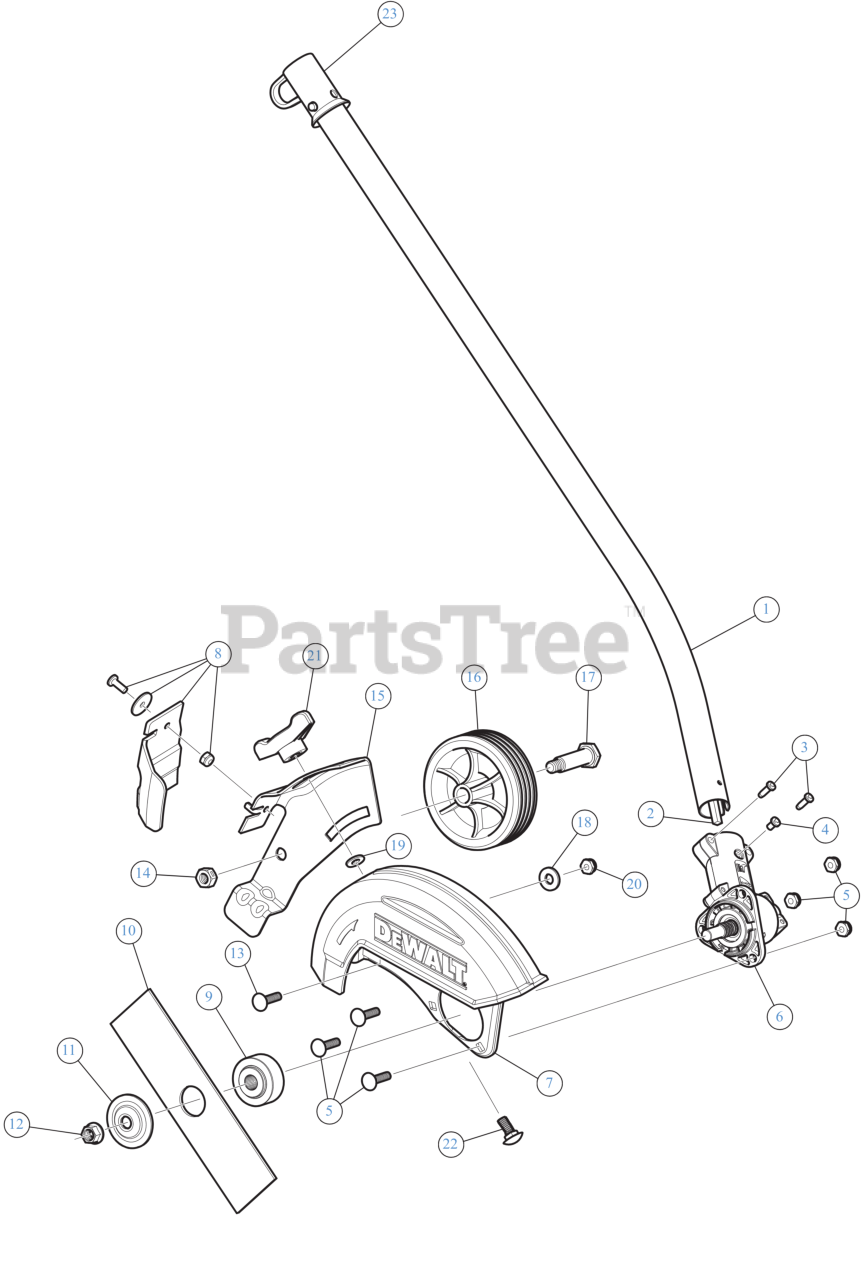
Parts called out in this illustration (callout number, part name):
1	BOOM ASSEMBLY
2	LOWER DRIVE SHAFT
3	SCREW #
4	SCREW, 8-32 x .312 P
5	BLADE LOCK NUT
6	GRBX ASSEMBLY
7	EDGER GUARD
8	GUARD (W/HDWR)
9	SPACER
10	EDGER BLADE
11	WASHER-BLADE CLAMP BRUSH CUT
12	BLADE LOCK NUT
13	CARRIAGE BOLT 1/4-20 x 1
14	LOCK NUT 3/8-16
15	BRACKET GUARD
16	WHEEL 3.75" (WHITE)
17	BOLT
18	FLAT WASHER
19	WASHER .406X1.0X.095
20	NUT 1/4-20 NYLOC
21	WING KNOB 5/16-18
22	CARRIAGE BOLT 5/16-18 x .75
23	HANGER
